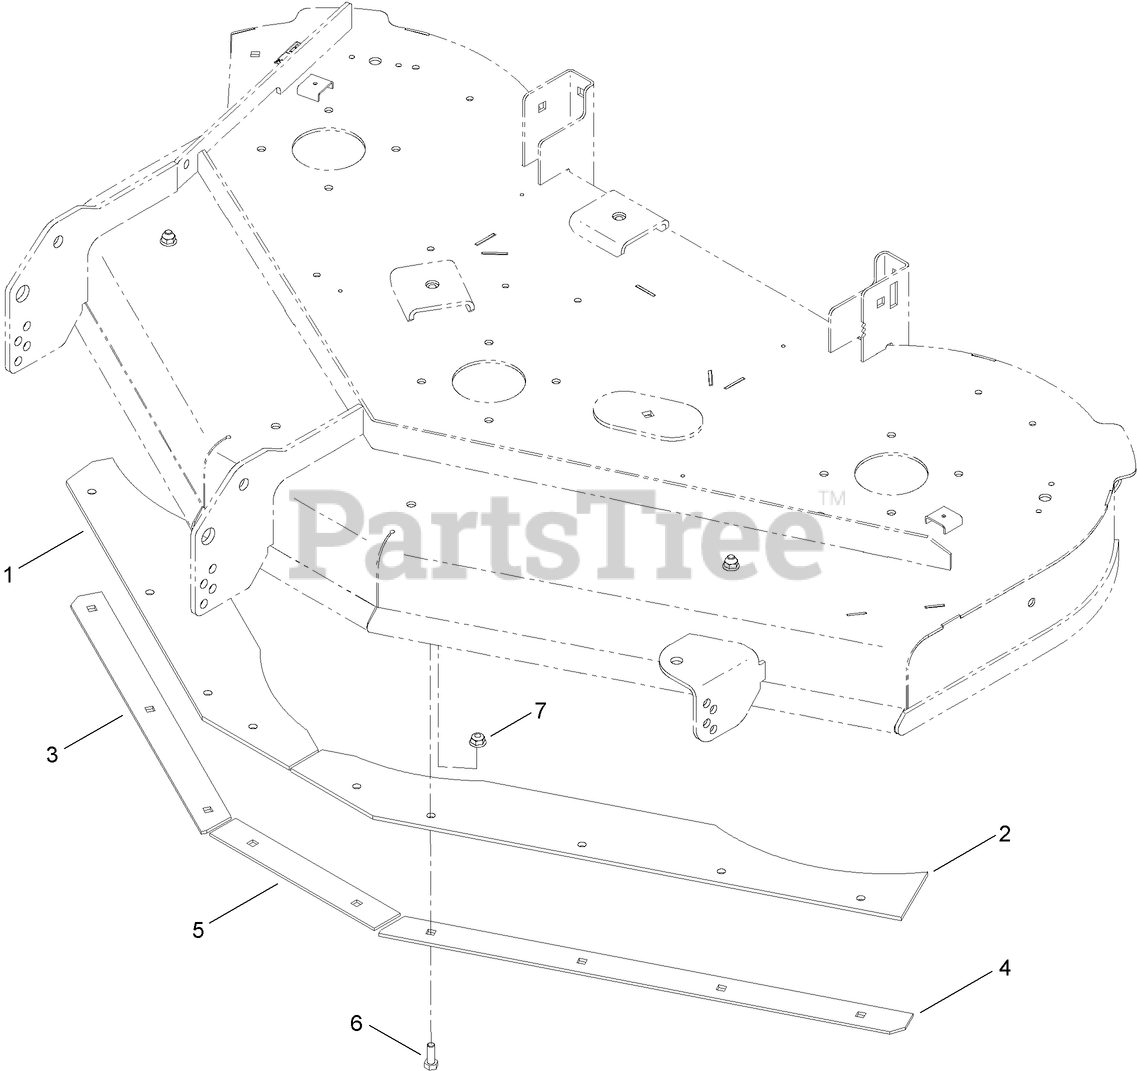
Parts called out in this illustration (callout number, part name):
1	SKIRT-RUBBER, RH
2	SKIRT-RUBBER, LH
3	PLATE-RH
4	PLATE-LH
5	PLATE-CENTER
6	SCREW-HH
7	NUT-HF, NI
